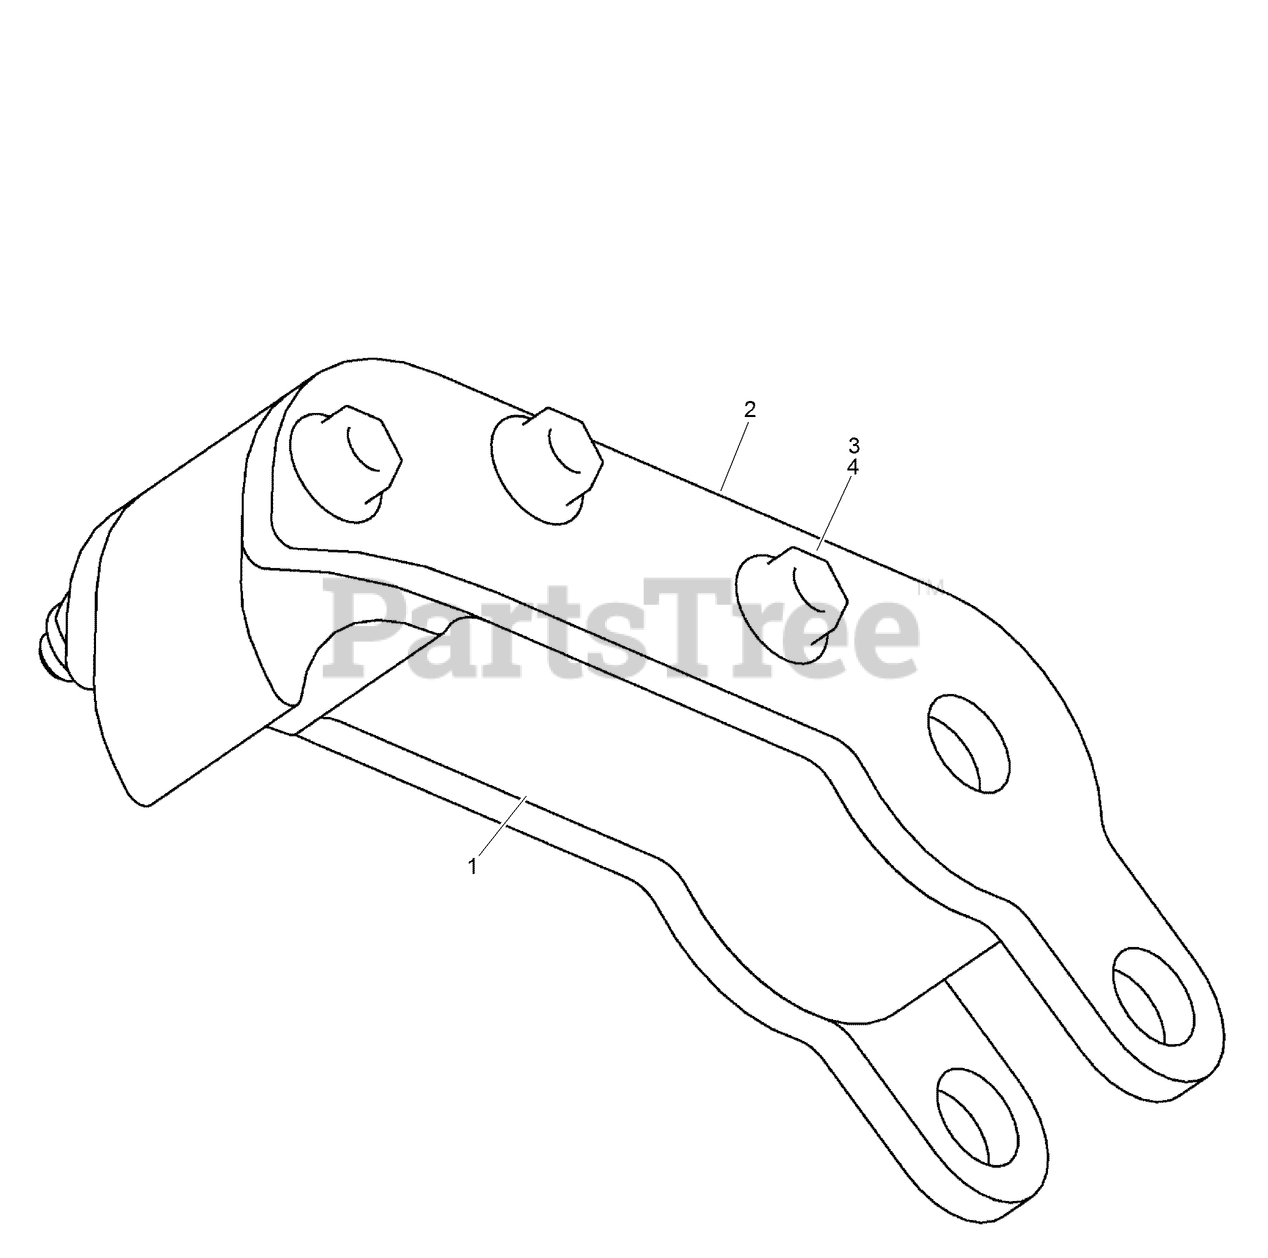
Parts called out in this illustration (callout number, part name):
1	INSERT-GRIPPER
2	PLATE - Gripper
3	SCREW-FLANGE
4	NUT-TORQUE, PREVAILING
